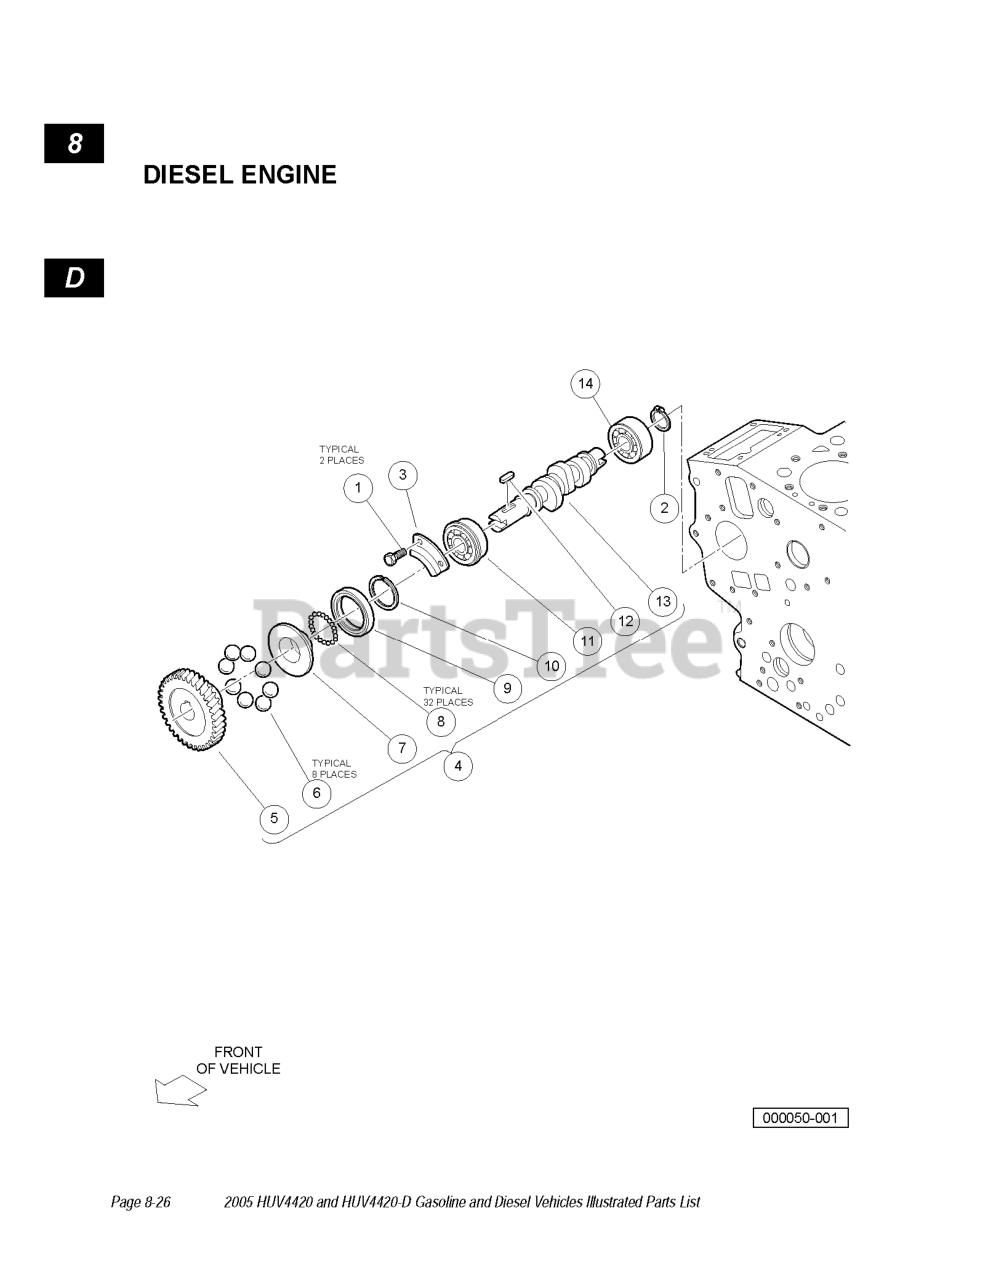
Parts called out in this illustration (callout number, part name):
1	BOLT, D722, CAM END
2	CIRCLIP, EXTERNAL
3	STOPPER, FUEL, C/SHAFT
4	ASSY, FUEL CAMSHAFT
5	GEAR, INJECTION PUMP
6	BALL, INJECTION PUMP
7	SLEEVE, GOVERNOR
8	BALL, GOVERNOR
9	CASE, GOVERNOR BALL
10	CIR-CLIP, GOV. SLEEVE
11	BEARING, BALL, LEFT
12	KEY, FEATHER, SHORT CAMSHAFT
13	CAMSHAFT, FUEL, SHORT
14	BEARING, BALL, FUEL CAM REAR
